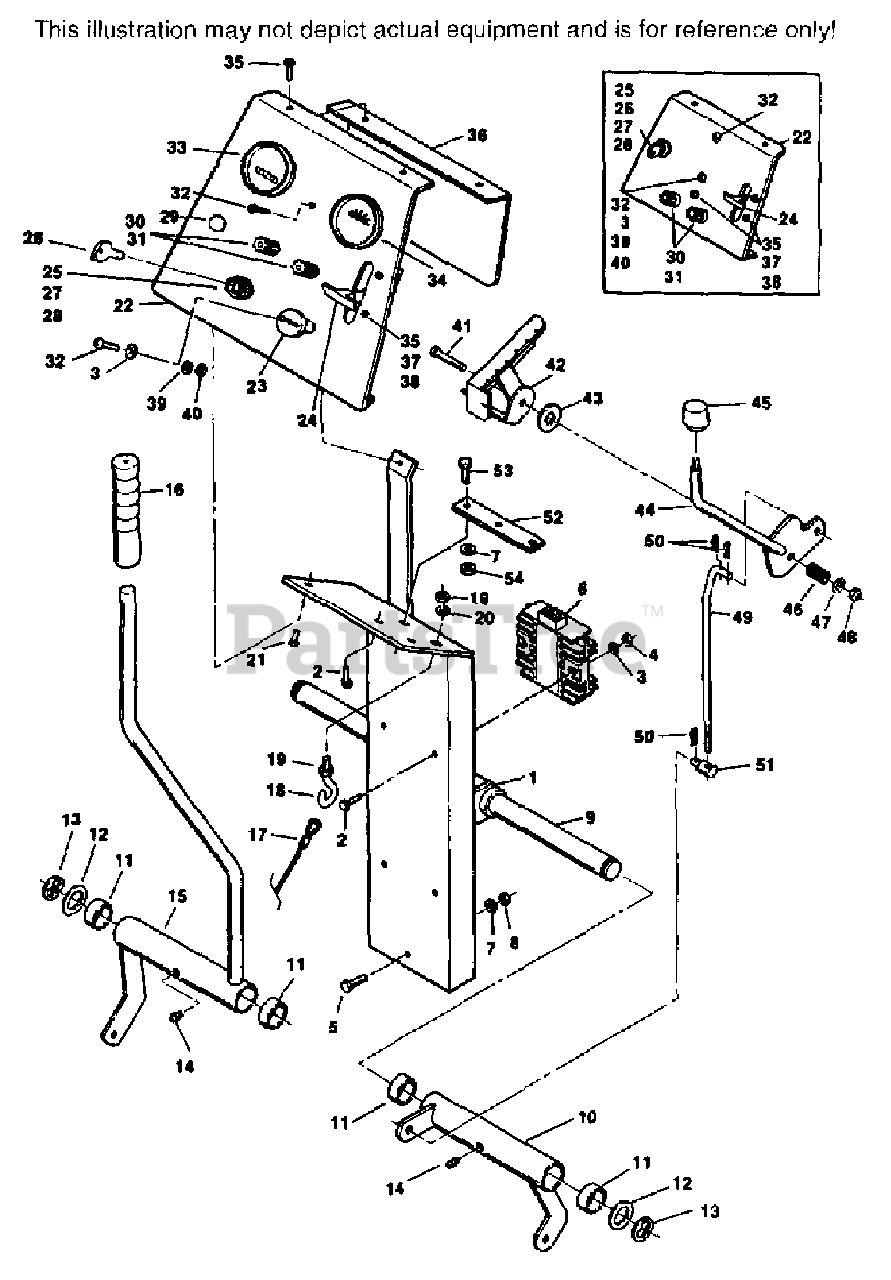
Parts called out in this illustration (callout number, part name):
1	CONSOLE SUPPORT WLD
3	WASHER, 9/32 X 5/8 X 16 GA.
7	LOCKWASHER, 5/16 SPRING
9	BELL CRANK SHAFT
10	SHIFTER WLD.(INCL. 11 & 14)
11	BRONZE BEARING
12	WASHER, 49/64 X 1-1/4 X 16 GA.
13	RETAINING RING, 3/4 EXT. "E"
14	GREASE FITTING, 1/4-28 STR.
15	MOWER ENGAGE WLD.(INCL. 11, 14, 16)
16	GRIP, MOWER LEVER
17	WINCH CABLE ASSEMBLY
18	EYEBOLT, 3/8-16 X 2
20	LOCKWASHER, 3/8 SPRING
24	THROTTLE CONTROL
25	STARTER SWITCH(INCL. 26-28)
26	KEY, IGNITION
27	LOCKWASHER, INT. TOOTH 5/8
28	HEX NUT, 5/8-11
30	FUSE HOLDER
31	FUSE, 20A
39	LOCKWASHER, 1/4 SPRING
42	SHIFT QUADRANT WLD.
43	WASHER, 3/8 X 2 X 16 GA.
44	SHIFTER HANDLE WLD.
45	SHIFTER KNOB
46	SPRING
47	WASHER, 13/32 X 13/16 X 16 GA.
49	SHIFTER CONNECTOR ROD
50	HAIR PIN COTTER, LARGE
51	SWIVEL JOINT
